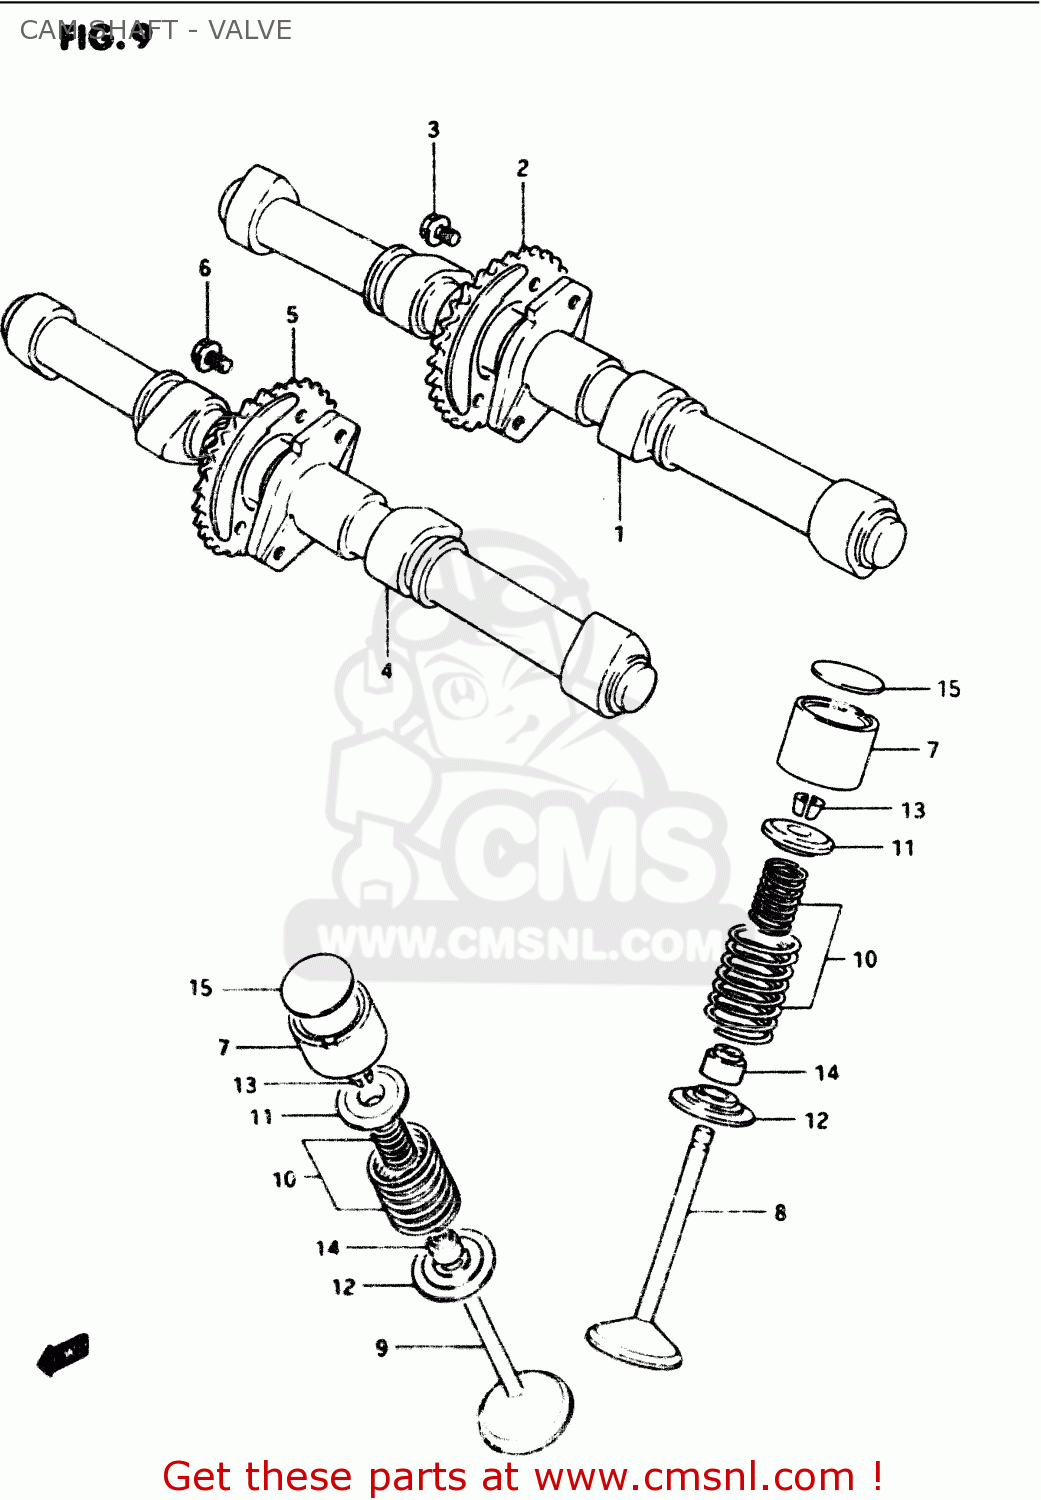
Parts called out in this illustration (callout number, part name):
1	CAMSHAFT,INTAKE
2	SPROCKET,INTAKE CAMSHAFT
3	BOLT(7X11)
4	CAMSHAFT,EXHAUST
5	SPROCKET,EXHAUST CAMSHAFT
6	BOLT(7X11)
7	TAPPET,INTAKE
8	VALVE,INTAKE
9	VALVE,EXHAUST
10	SPRING SET,VALVE
11	RETAINER,VALVE SPRING
12	SEAT,VALVE SPRING
13	COTTER VALVE
14	SEAL,OIL(7X14.4X9)
15	SHIM,TAPPET(T:2.15)
